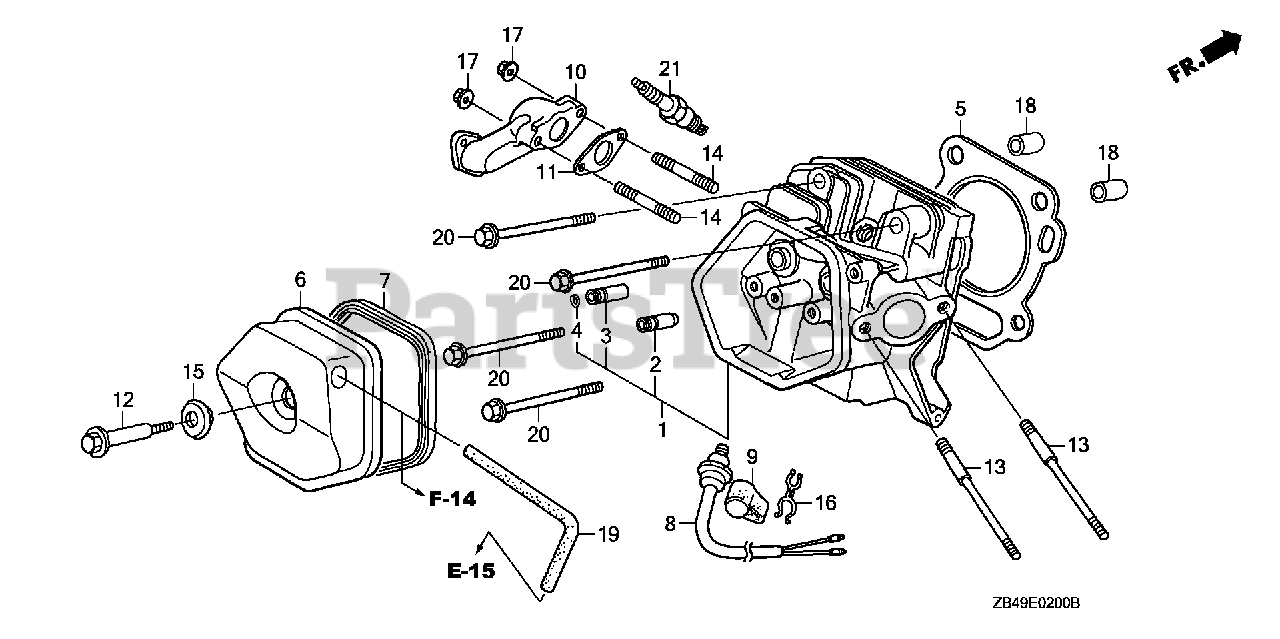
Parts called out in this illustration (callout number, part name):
1	CYLINDER HEAD
2	GUIDE, VALVE (OVER SIZE)
3	GUIDE, EX. VALVE (OVER SIZE)
4	CLIP, VALVE GUIDE
5	GASKET, CYLINDER HEAD
6	COVER, HEAD
7	GASKET, HEAD COVER
12	BOLT, HEAD COVER
13	BOLT, STUD (8X123)
14	BOLT, STUD (8X47)
14	BOLT, STUD (8X32)
15	WASHER, HEAD COVER
18	PIN, DOWEL (12X20)
19	BULK HOSE, VACUUM (11X1000) (11X100)
19	BULK HOSE, VACUUM (11X1000) (11X105)
20	BOLT, FLANGE (10X80)
21	SPARK PLUG (BPR5ES) (NGK)
21	SPARK PLUG (W16EPR-U) (DENSO)
